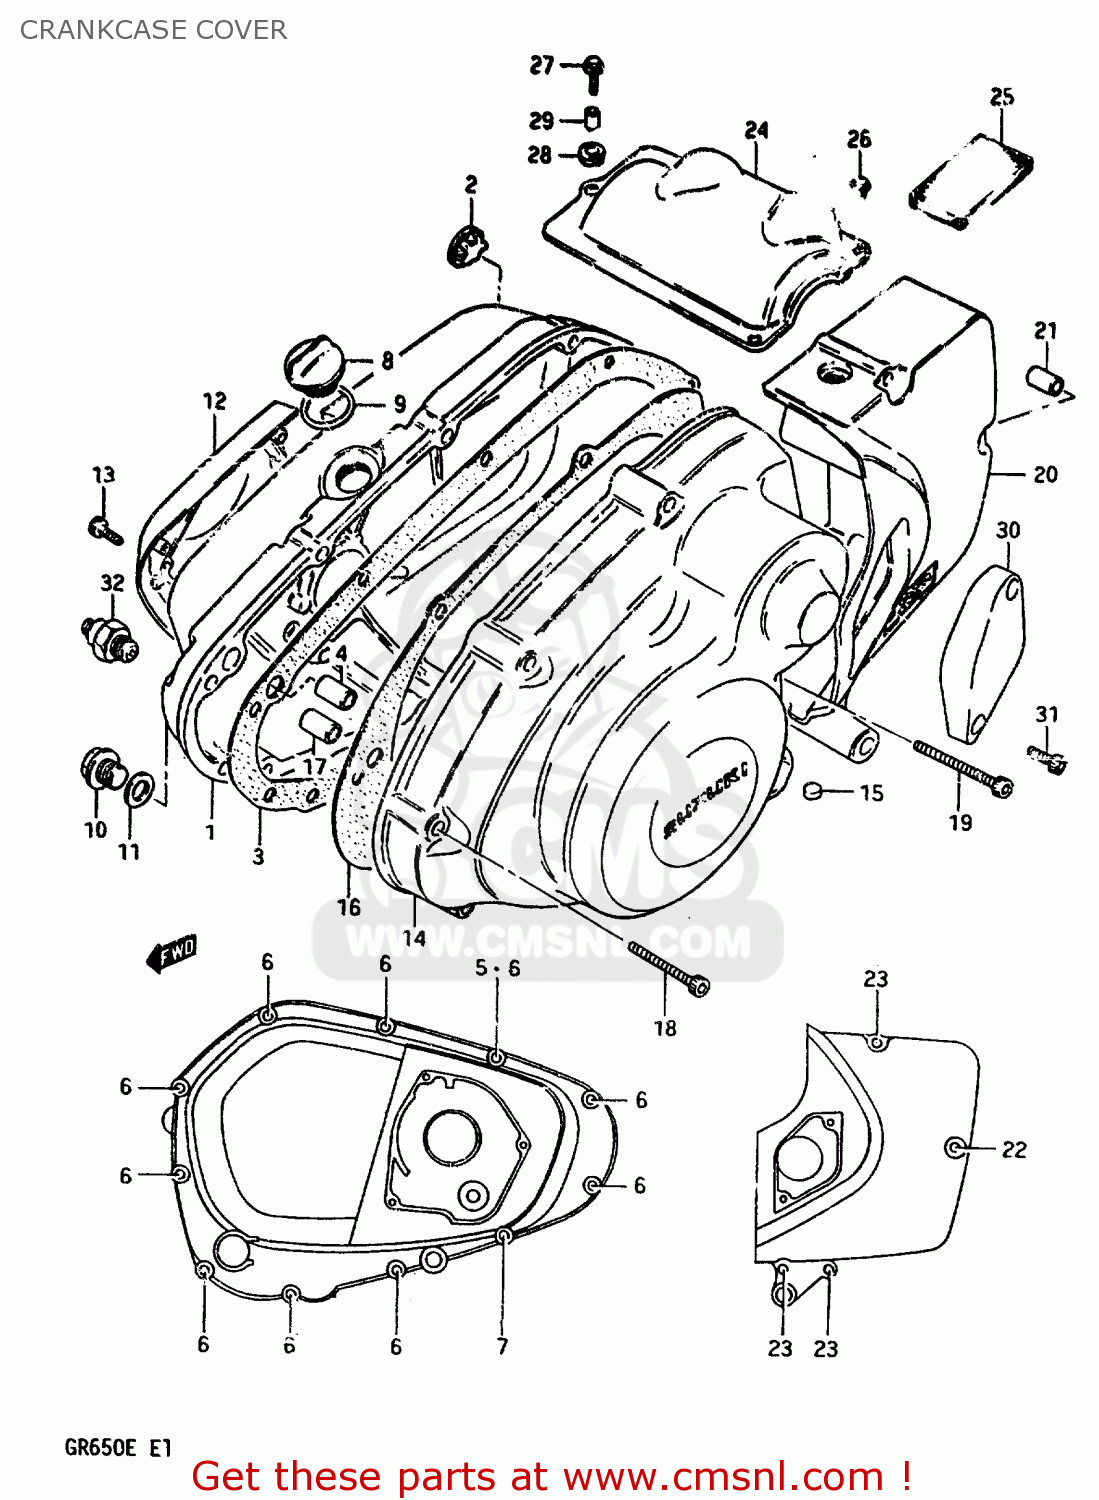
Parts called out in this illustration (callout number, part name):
1	COVER,CLUTCH
2	LENS,OIL LEVEL CHECK
3	GASKET,CLUTCH COVER (MCA)
4	PIN (11X20)(SUS)
5	WASHER
6	BOLT (6X30)
7	BOLT (6X40)
8	PLUG(20X10)
9	O RING(D:3.1,ID:16.8)
10	PLUG (14X12)
11	GASKET(14X19.2X2) (NAS)
12	COVER,CONTACT BREAKER
13	BOLT
14	COVER,MAGNETO
15	MAGNETO
16	GASKET,MAGNETO COVER
17	PIN (11X20)(SUS)
18	BOLT (6X40)
19	BOLT (6X50)
20	COVER,ENGINE SPROCKET
21	PIN
22	BOLT (6X65)
23	BOLT (6X50)
24	COVER,STARTER MOTOR
25	DAMPER,STARTER MOTOR CLUTCH
26	BOLT
27	BOLT 5X16
28	CUSHION
29	SPACER (5.2X9X5)
30	CAP,CLUTCH RELEASE ADJUST
31	BOLT
32	SWITCH ASSEMBLY
